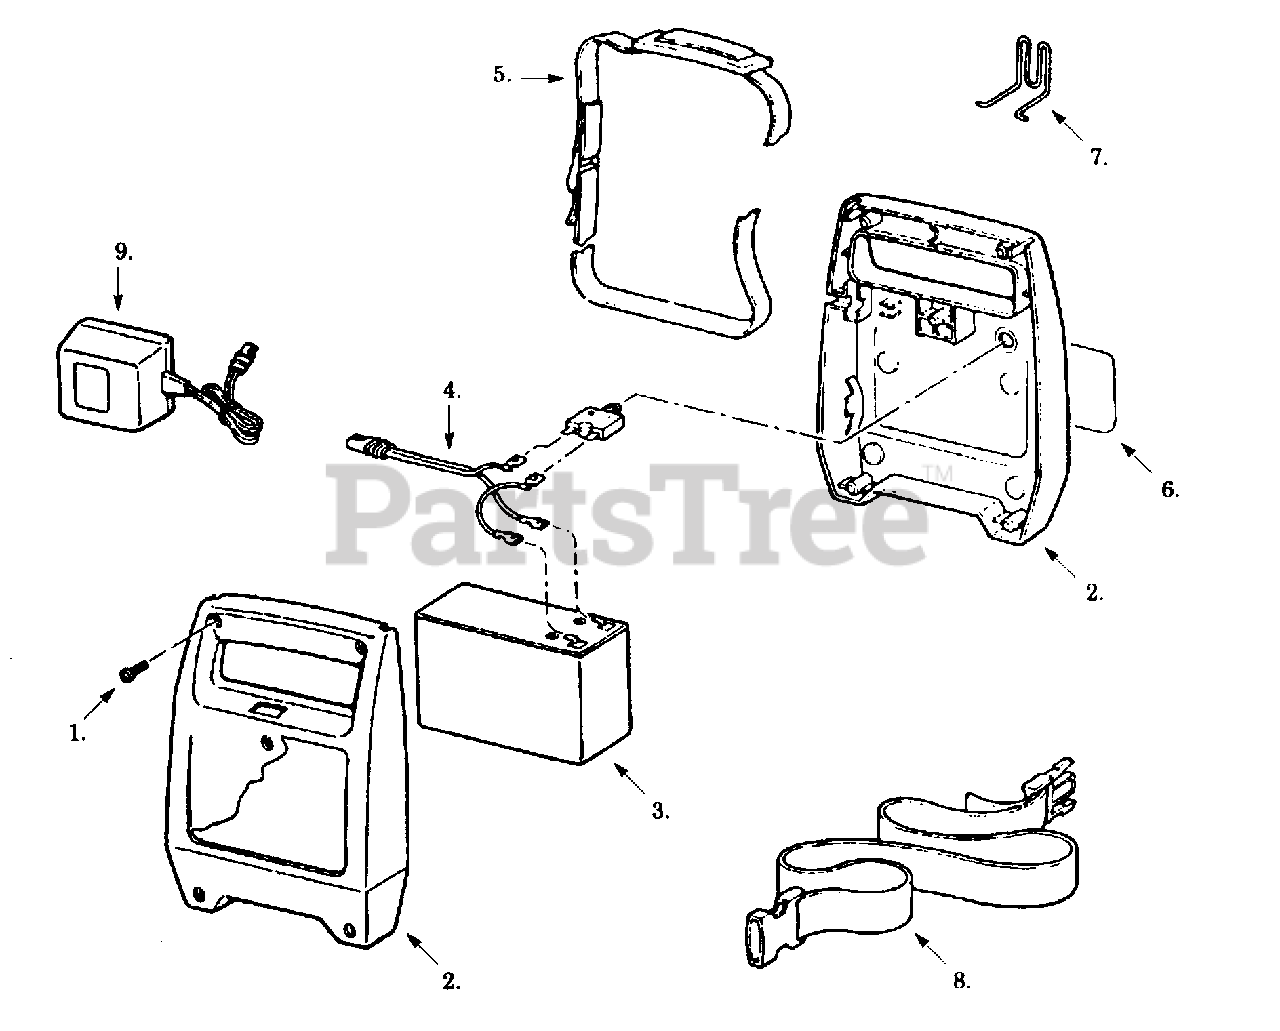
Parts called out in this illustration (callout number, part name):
2	Housing Set
4	Harness Ass'y. (w/ Circuit Breaker)
5	Shoulder Strap
6	Warning Decal
7	Belt Hook
8	Waist Belt
9	Battery Charger
